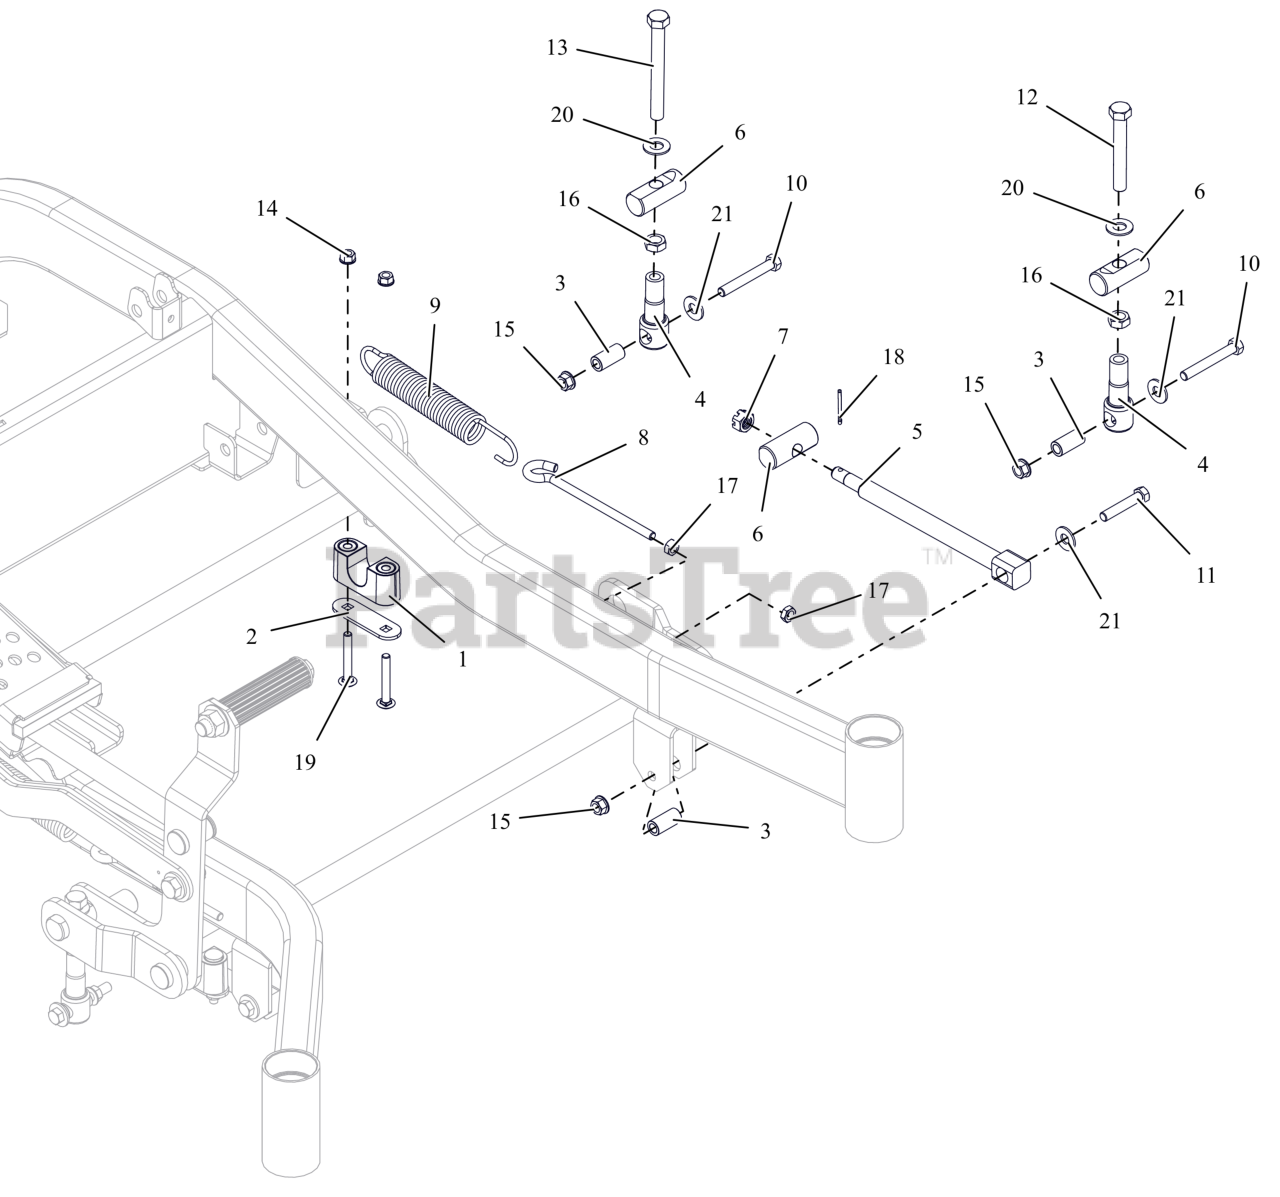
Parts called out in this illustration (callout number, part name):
1	ASM-BUSHING, DECK LIFT
2	PLATE, BEARING SUPPORT
3	SPACER, DECK LEVELING
4	LINK, DECK LIFT FORMED
5	DRAG,LINK-HD
6	PIN, DECK LIFT
7	NUT-SL .50-13
8	BOLT,.38-16 X 5.25-.62 DIA EYE
9	SG-TENS .162X1.25X8.25 WLD 25
10	BLT, HEX .38-16X2.75 G8 ZCC
11	BLT,HEX .38-16X2.00 G5 ZCC
12	BLT, HEX .50-13X3.50F G5 ZCC
13	BLT, HEX .50-13X4.50F G8 ZCC
14	NUT,LK-CTR-FLG .31-18 GF ZCC
15	NUT-LK-TOP-FLG .38-16 ZC120
16	NUT-JAM .500-13 G2 ZCC
17	NUT-JAM .375-16 G2 ZCC
18	PIN,CTR.12X1.25EXTPRSQCT ZC120
19	BLT, RHSSN.31-18X2.25 G5 ZCC
20	WSHR, FLT .557X1.040X.102 ZCC
21	WSHR,FLT .438X1.00X.083 ZCC
